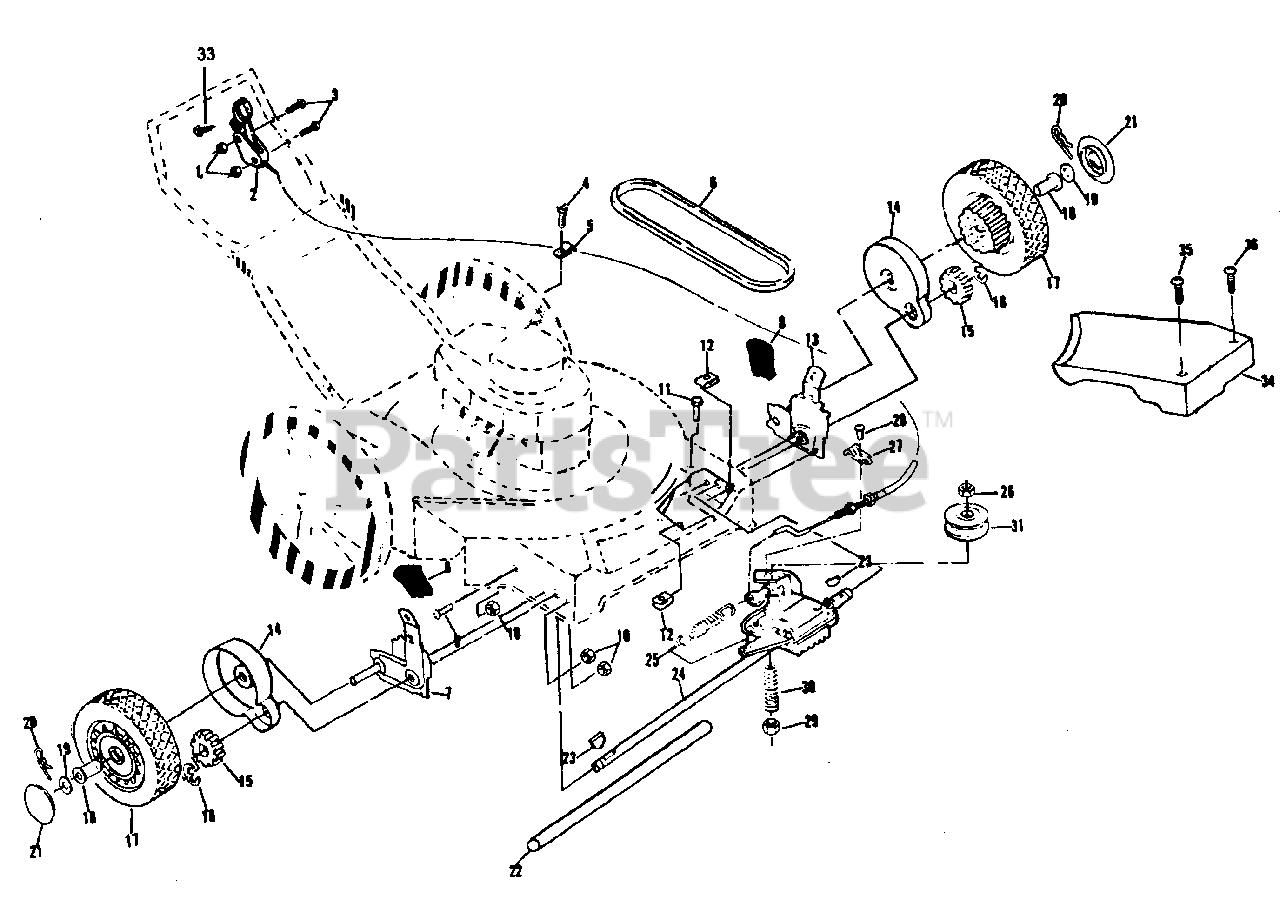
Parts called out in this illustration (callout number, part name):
1	Locknut 10-24 (AYP part number)
2	Drive Control (AYP part number)
3	Pan Head Machine Screw 10-24 x 2 (AYP part number)
4	Hex Washer Head Tapping Screw 10-24 x 1/2 (AYP part number)
5	Guide Clip (Housing) (AYP part number)
7	Wheel Adjuster Assembly (Right) (AYP part number)
8	Selector Knob
9	Flat Head Machine Screw 1/4-20 x 3/4 (AYP part number)
10	Locknut 1/4-20 (AYP part number)
11	Hex Head Bolt 1/4-20 x 2-3/4 (AYP part number)
12	Speed Nut (AYP part number)
13	Wheel Adjuster Assembly (Left) (AYP part number)
14	Dust Cover (AYP part number)
15	Pinion (AYP part number)
17	Wheel & Tire Assembly 8.0 x 1-3/4
18	Wheel Bushing (AYP part number)
19	Washer (AYP part number)
20	Retainer Clip (AYP part number)
21	Hubcap (AYP part number)
22	Drive Shaft Cover (AYP part number)
23	Woodruff Key #3 (AYP part number)
24	Gear Case (AYP part number)
26	Locknut (AYP part number)
27	Cable Clamp (Adj. Bracket) (AYP part number)
28	Pan Head Self Tapping Screw #10-24 (AYP part number)
29	Locknut 1/4-20 (AYP part number)
30	Spring (AYP part number)
31	Drive Pulley (AYP part number)
33	Screw, Pan Head, Hi-Lo 10-16 x .63 (AYP part number)
34	Drive Cover (AYP part number)
35	Pan Head Machine Screw #10-24 x 1-3/4 (AYP part number)
36	Pan Head Machine Screw #10-24 x 2 3/4 (AYP part number)
